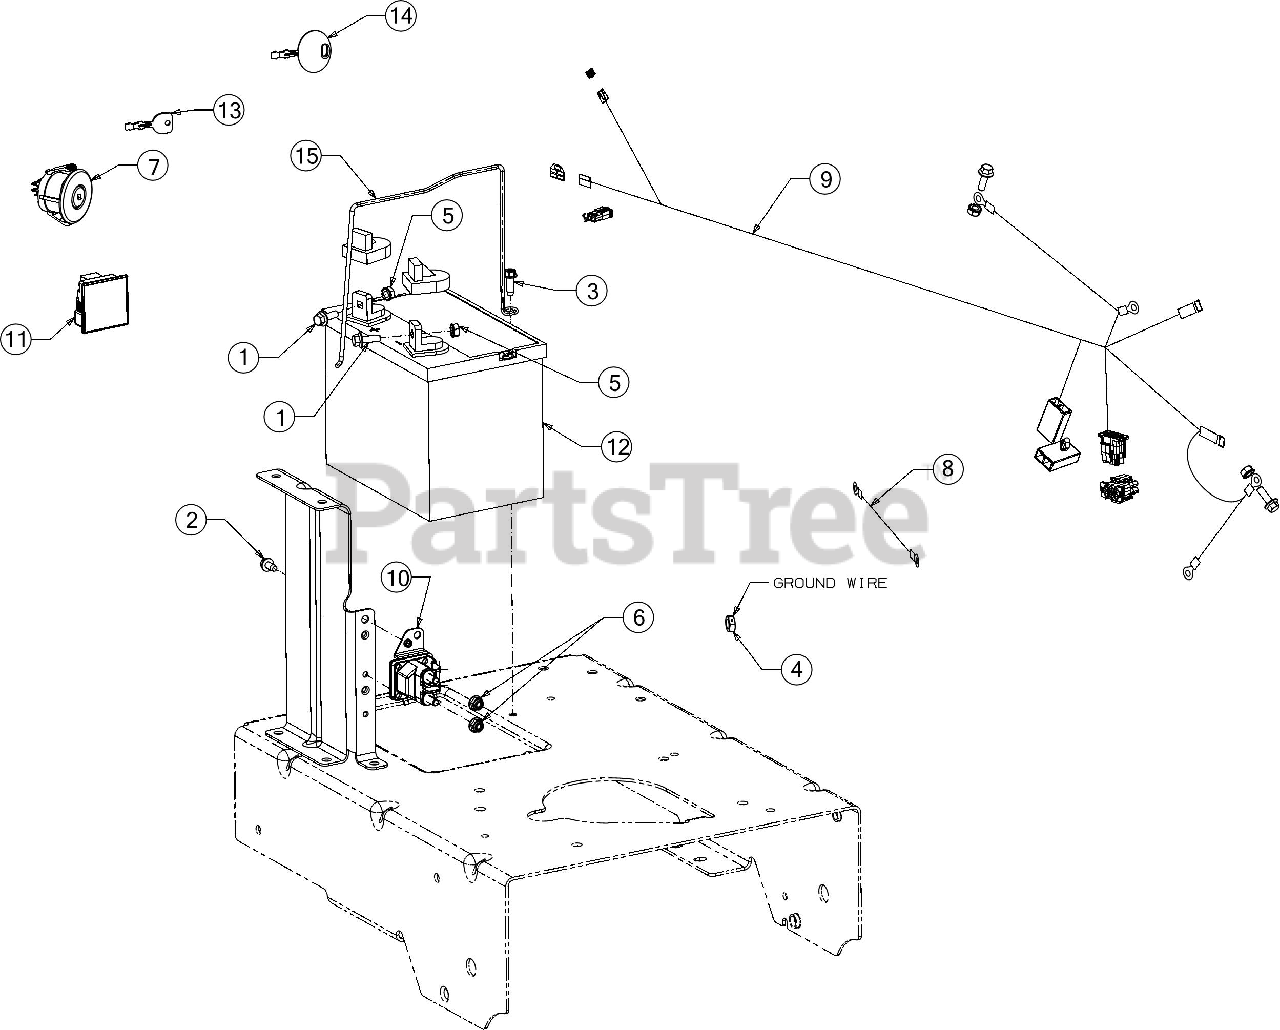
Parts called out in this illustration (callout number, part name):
1	SCREW 1/4-20 x .75 GR5
2	SCREW 1/4-20 X.500
3	SCREW 1/4-20 x .750
4	JAM LOCK NUT
5	SEMS NUT 1/4-20
6	FLANGE LOCK NUT
7	KEY SWITCH 3 POSITION
8	STARTER HARNESS
9	HARNESS
9	SCREW 1/4-20 x .75 GR5
9	SEMS NUT 1/4-20
10	SOLENOID-12V 100A
11	HOUR METER
12	BATTERY
13	IGNITION KEY
14	IGNITION KEY
15	BATTERY HOLD DOWN STRAP
